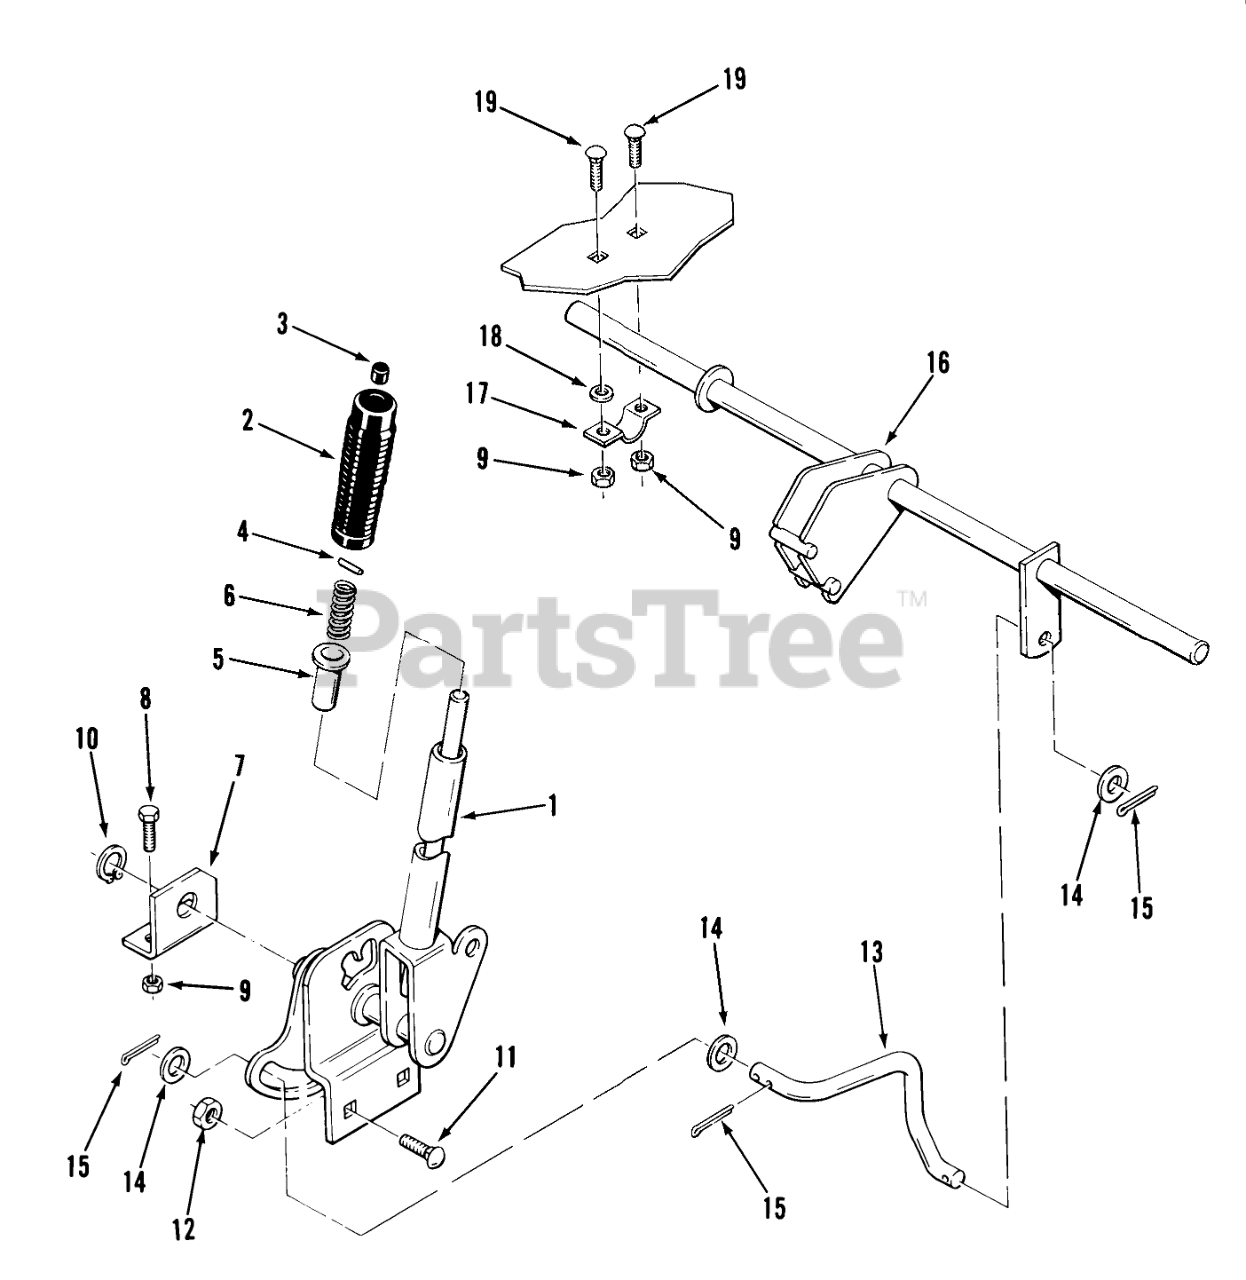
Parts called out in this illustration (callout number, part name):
1	Lift Lever
2	HANDGRIP
3	CAP-ROD, PLUNGER
4	PIN-SPIROL
5	RETAINER-SPRING
6	SPRING-COMPRESSION
7	BRACKET-INNER R
8	Bolt
9	Nut
10	Snap Ring
11	Bolt-Carriage
12	Nut
13	ROD LIFT
14	Washer
16	ASM-REAR LIFT R
17	CLAMP
18	Washer
19	CARRIAGE BOLT -4
